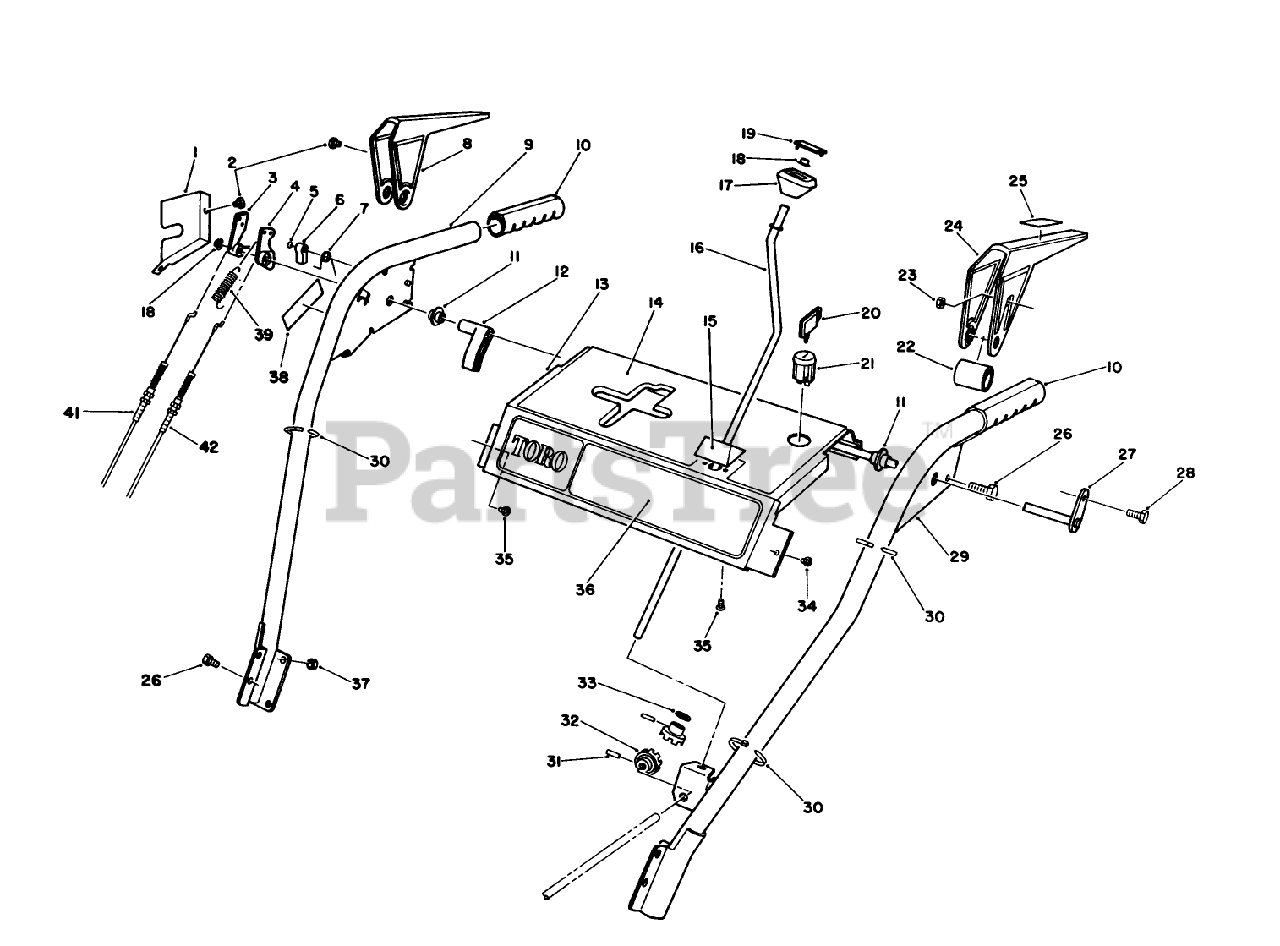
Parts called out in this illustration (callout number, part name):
1	Cover Lever Lock
2	SCREW-HH
3	TANG-LOCKING
4	CAM-RELEASE
5	E-RING-RETAINER
6	LATCH-LOCKING
7	SPRING-TORSION
8	Lever-Impeller
9	Handle-R.H.
10	GRIP-HANDLE
11	BUSHING-LEVER
12	LEVER-TRIP
13	Panel-Control
14	Decal-Panel, Top
15	PLATE-GUIDE
16	CRANK-ROD, CHUTE
17	KNOB-CONTROL, CHUTE
18	RETAINER-PUSH ON
19	COVER-KNOB
20	KEY-IGNITION
21	SWITCH
22	NUT-LOCK, NI
23	Lever-Traction
24	SPACER-LEVER, TRACTION
25	DECAL-LEVER
26	SCREW-HHF
27	CROSS ROD ASM
28	SCREW-HWH
29	Handle-L.H.
30	TIE-CABLE
31	PIN-SPRING
32	GEAR-UNIVERSAL
33	WASHER-RUBBER
34	SCREW-HWHTF
35	SCREW-PPH
36	DECAL-FRONT PANEL (828)
37	NUT-LOCK, NI
38	DECAL-WARNING
39	Spring-Extension
40	CABLE-TRACTION
41	CABLE-IMPELLER
